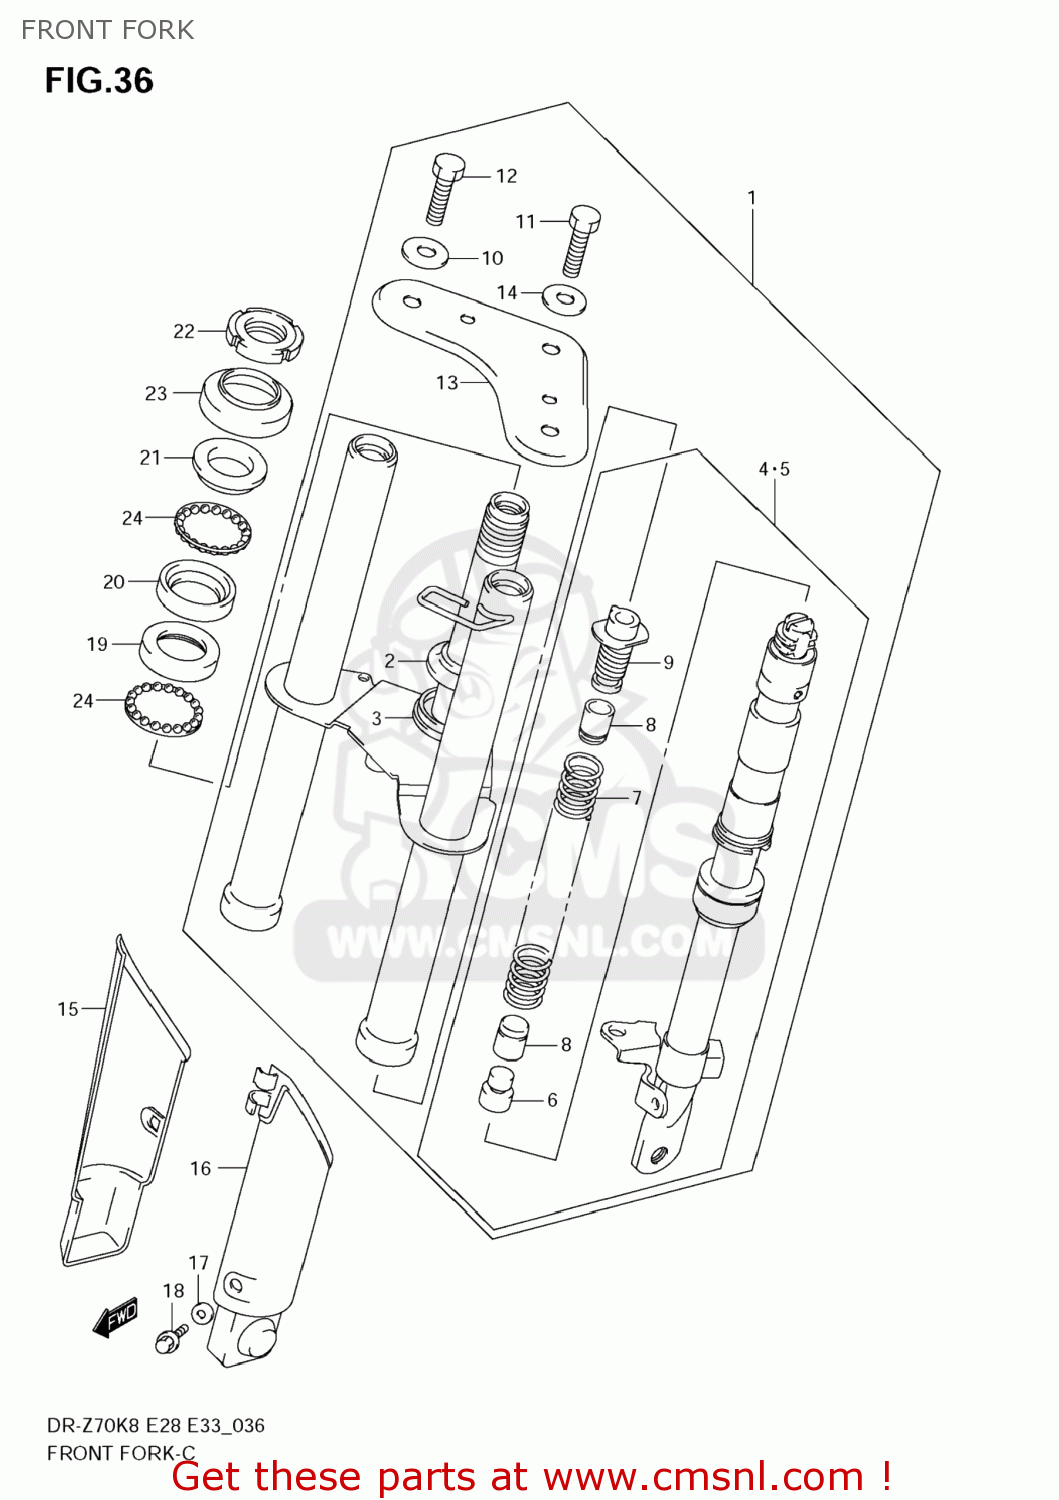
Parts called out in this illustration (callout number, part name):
1	FORK SET,FR
2	RACE,STEERING OUTER LWR
3	SEAL,STEERING LWR
4	TUBE ASSY,FR FORK LWR,R
5	TUBE ASSY,FR FORK LWR,L
6	STOPPER
7	SPRING
8	STOPPER,RUBBER
9	SPRING,JOINT B
10	WASHER(10X30X2.5)
11	BOLT
12	BOLT
13	BRACKET,UPR
14	WASHER(10.5X24X3.2)
15	PROTECTOR,FR FORK,R
16	PROTECTOR,FR FORK,L
17	WASHER
18	BOLT
19	RACE,STEERING INNER LWR
20	RACE,STEERING INNER UPR
21	RACE,STEERING OUTER UPR
22	NUT,STEERING STEM(25X44X10)
23	DUST SEAL,STEERING UPR
24	BEARING(27X40.5X5)
